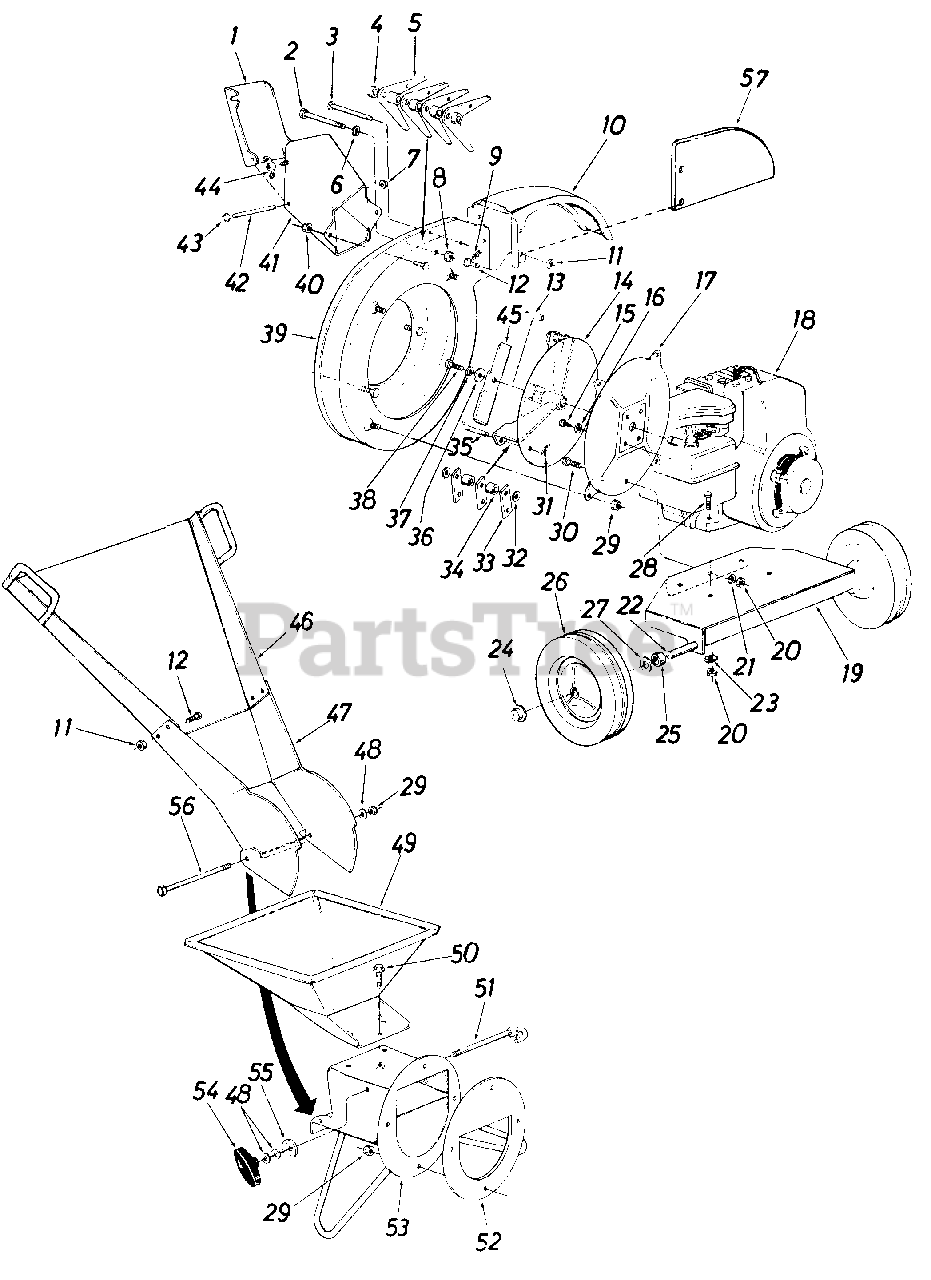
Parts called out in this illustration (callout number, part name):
1	Door Chip It
2	Hex Bolt 1/2-20 x 4.50" Lg.
3	Clevis Pin
4	Flail Spacer 7/32" Lg.
5	Cutting Finger
6	L.-Wash. 1/2" Scr.
7	Palnut3/16" Dia.
8	Hex Jam Nut 1/2-20 Thd.
9	Cotter Pin 3/32" Dia. x 3/4" Lg.
10	Chute Deflector
11	L.-Nut 1/4-20 Thd.
12	Hex Bolt 1/4-20 x .50" Lg.
13	Sq. Key 1/4" x 2.00" Lg.
14	Impeller Assembly
15	Hex Bolt 5/16-24 x 3/4" Lg.
16	L-Wash . 5/ 1 6 " Scr.
17	Hopper to Engine Mtg. Plate
18	Engine
19	Engine Mounting Plate
20	Hex Nut 5/16-24 Thd:
21	L.-Wash. 5/16" Scr.
22	1 Shaft
23	Special L.-Wash. 5/16" I.D.
24	Push Cap
25	Spacer
26	Wheel Ass'y.-Comp.
27	Fl.-Wash..50" I.D.
28	Hex Bolt 5/16-24 x 1.50" Lg.
29	Elastic Stopnut 5/16-18 Thd.
30	Hex Bolt 5/16-24 x .62" Lg.
31	Cotter Pin 1/8" Dia. x 1.00" Lg.*
32	Fl-Wash. .531" I.D. x 93 O.D. x .09
33	Flail
34	Flail Spacer 23/32" Lg.
35	Clevis Pin .50" Dia. x 3.0" Lg.
36	Fl.-Wash. .406" I.D. x 1.25" O.D. Hdn.
37	L.-Wash. 3/8" Scr. H.D.
38	HexBolt3/8-24x 2.00" Lg. H.T.
41	Upper Guide Extension Ass'y.
42	H inge Pin
43	Palnut3/16" Dia.
44	Wing Nut Elastic 1/4-20 Thd
47	Guide Extension
48	Fl.-Wash. 5/16" Scr.
49	Hopper Assembly
50	Hex Wash. Hd. Self-Tap Scr. 5/16-18 x .50" Lg.
51	Clamp Rod Assembly
52	Back-Up Plate
53	Inlet Guide Assembly
54	Knob Ass'y.
55	Stop Washer
56	Hex Bolt 5/16-18x 8.38" Lg.
57	Deflector Side Plate
